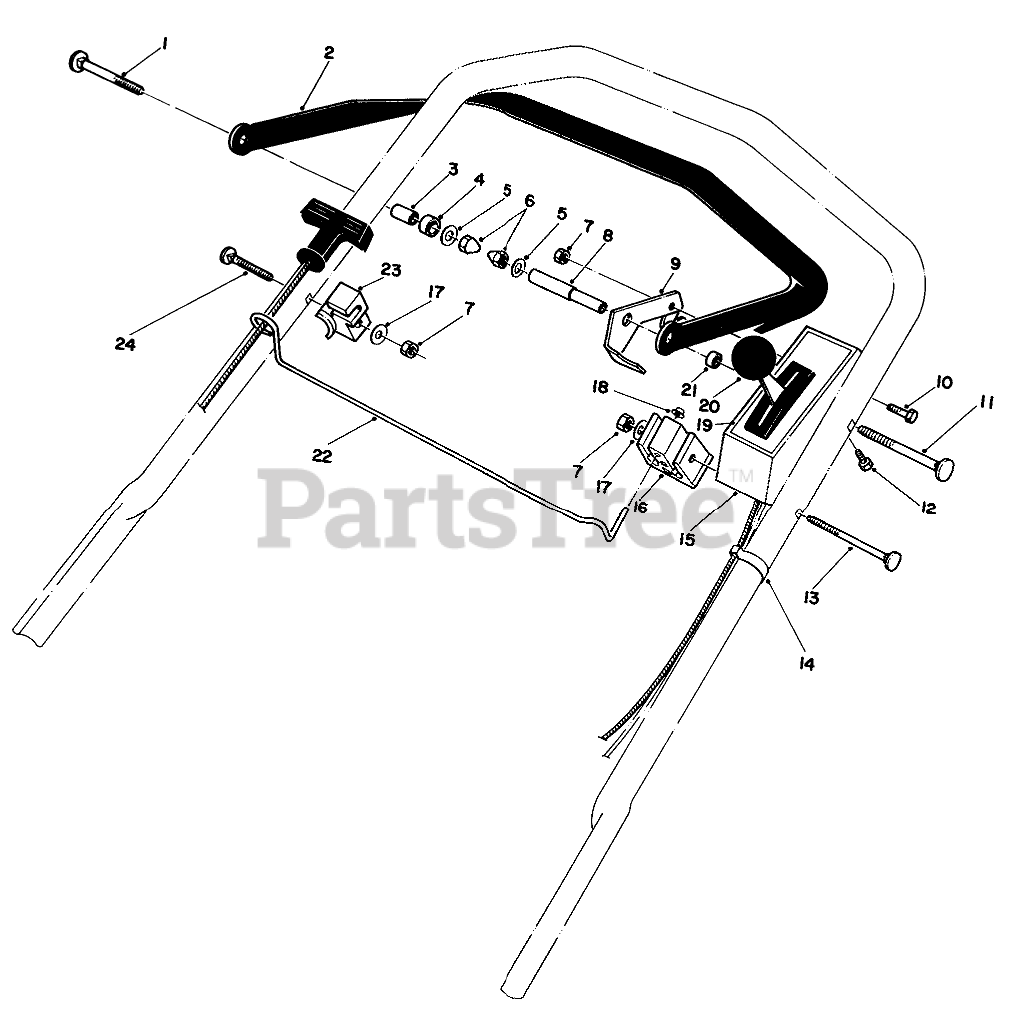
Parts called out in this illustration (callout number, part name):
1	5/16-18 X 2 HNDLE SCREW
2	Bar-Control
3	Spacer
4	SPACER-NYLON
5	WASHER-PLAIN
6	NUT-LOCK, CAP
7	NUT-LOCK, NI
8	Spacer
9	Lever-Control
10	SCREW-HH
11	5/16-18X3.75 HDLE SCREW
12	SCREW-HWHTF
13	SCREW-HANDLE
14	BOWDEN CLIP
15	Cover-Control (Incl. Ref. #19)
16	SUPPORT-CABLE
17	WASHER-FLAT
18	NUT-SPEED
19	OBS DECAL
20	Control-Choke
21	Nylon Spacer
22	ROPE ROD PLATED
23	ROD CATCH
24	SCREW-HANDLE
